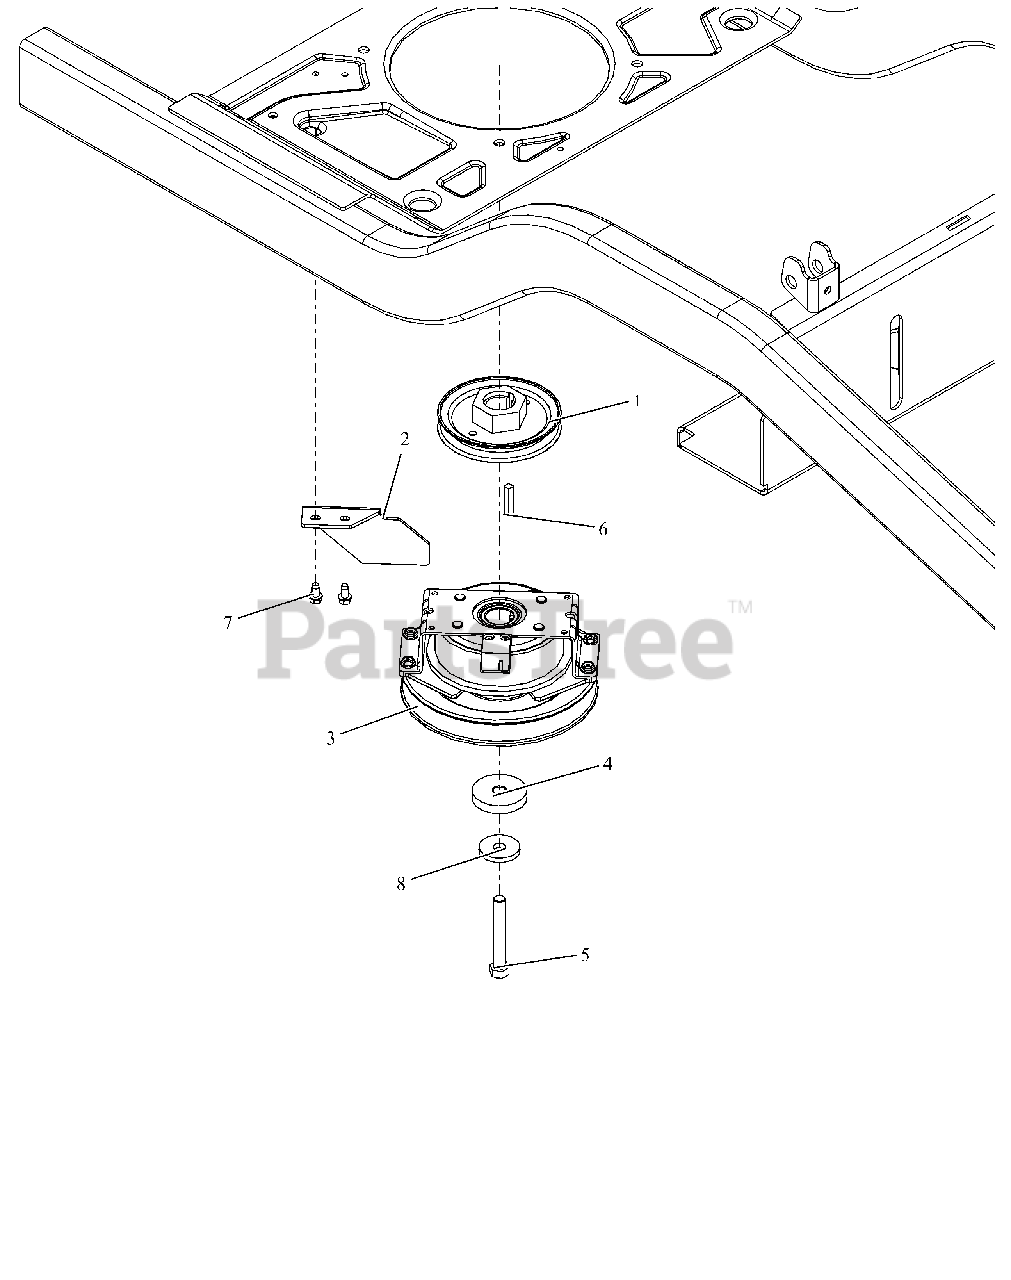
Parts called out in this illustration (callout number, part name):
1	WLDMT,PULLEY-4.50ODX1.003
2	BRKT, CLUTCH STOP HD
3	CLUTCH, OGURA DBL SPRG
4	SPACER, .474/.459X2.00X.350
5	BLT, HEX 0.4375-20X3 G8 ZCC NT
6	KEY-SQ .25 X 1.25 X .25 SAE
7	SCR-TAP .25-20X.50 HWH ZCC
8	WASHER, 7/16" SPRING DISK
